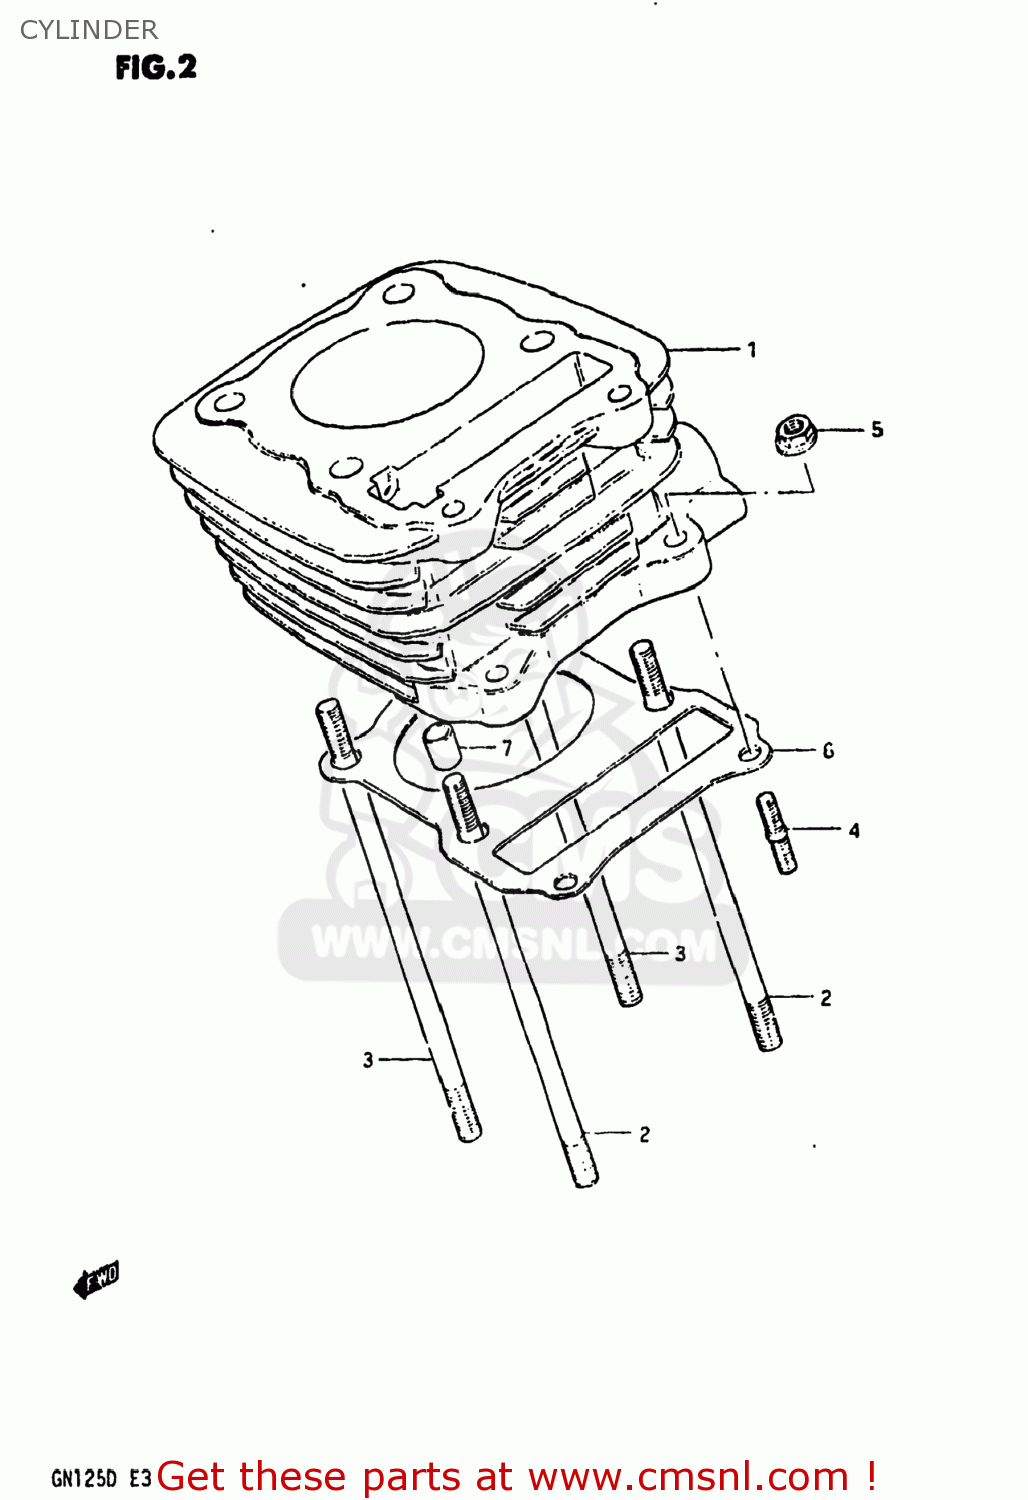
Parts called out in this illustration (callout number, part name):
1	CYLINDER
2	BOLT,STUD
3	BOLT,STUD
4	STUD 6X25
5	NUT
6	GASKET,CYLINDER (MCA)
7	PIN
